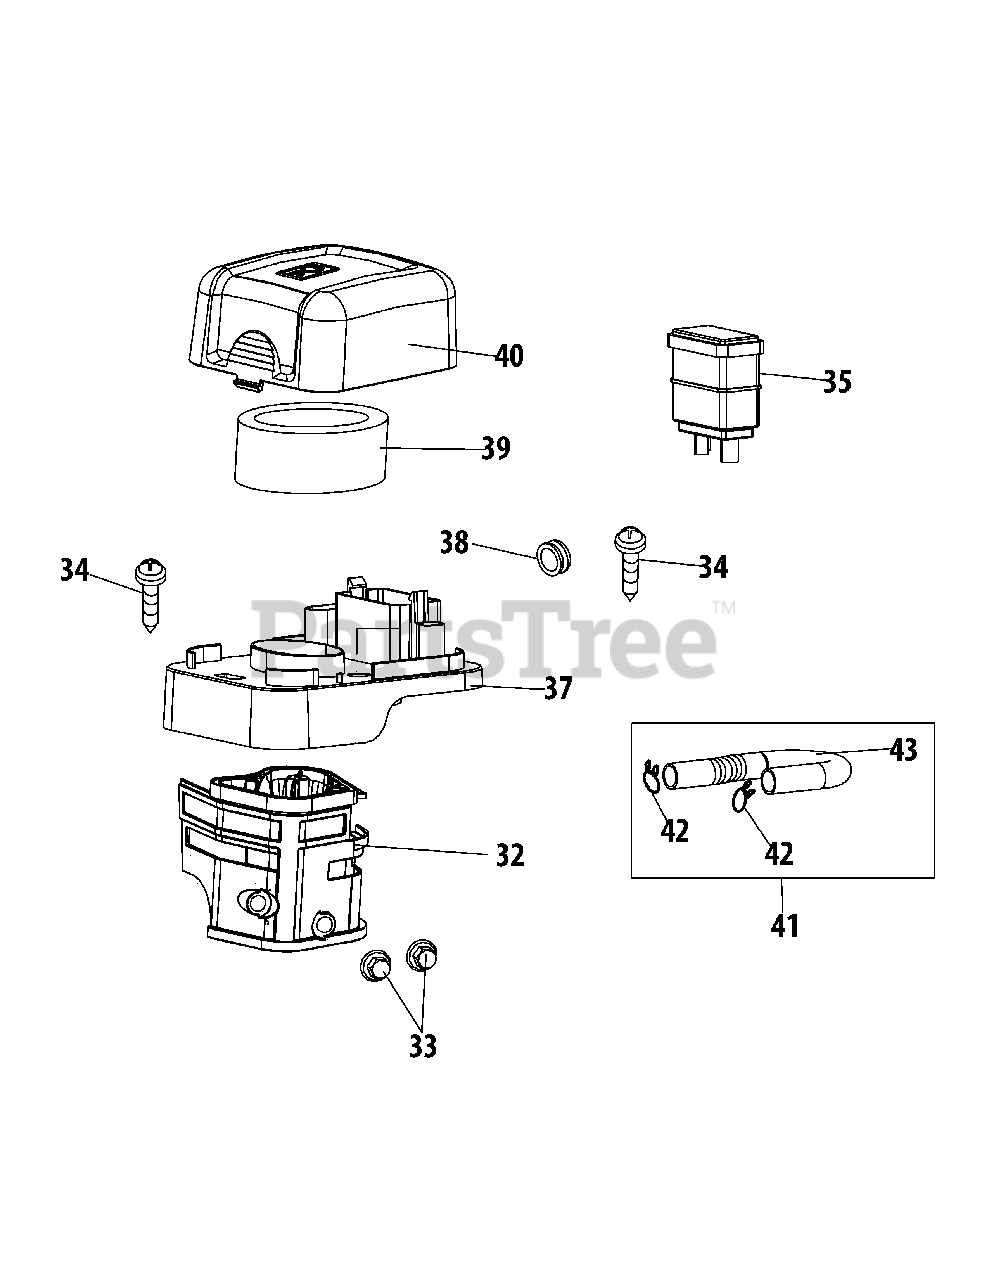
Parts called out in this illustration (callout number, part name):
32	Air Cleaner Housing
34	Self-Tapping Bolt M4.2×16
35	Carbon Canister
37	Silencer Plate
38	Rubber Shock Pad
39	Air Filter Assembly
40	Air Filter Cover
41	Primer Hose
43	Exhaust Piping
